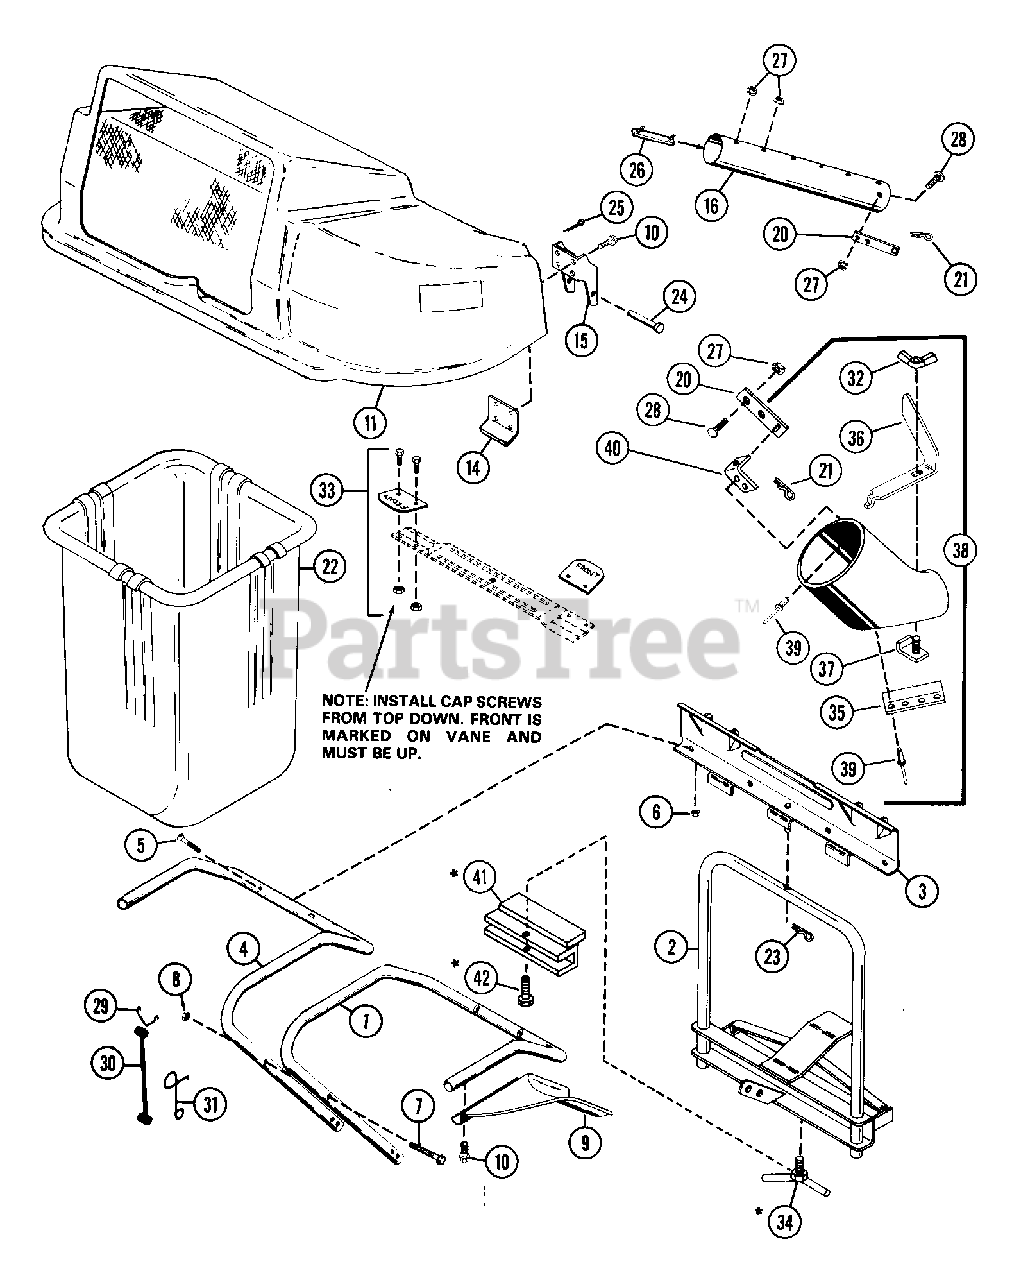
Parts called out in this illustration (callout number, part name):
1	TUBE R.H. SUPPORT
2	ATTACHMENT FRAME
4	TUBE L.H. SUPPORT
5	SCR-MCH .31-18X1.50 CROVCNTRS
6	NUT-LK-NYL.312-18 PL
7	BLT-HEX .25-20X2.25 GR2
8	NUT-LK-CTR .250-20 PL
9	SUPPORT TUBE
10	BLT-SCRHFWH .25-20X.62 PL
11	GRASS CATCHER COVER ASSEMBLY
14	RETAINER
16	TUBE BLANK
20	STRAP
21	PIN-HAIR INT .09X.188 PL
23	PIN-HAIR INT .08X.38X1.42 YWZC
24	CLEVIS PIN
25	PIN-COTR .06X.50
27	NUT-LK-FLG .250-20 PL
28	BLT-RDHDSQNK .25-20X.50 SHT PL
30	BATTERY STRAP
31	HOOK
32	NUT-WING W/INSERT .312 - 18
33	SERVICE VANE PACKAGE
34	T-HANDLE BOLT
35	EXTENSION CHUTE
36	BOOT STRAP
37	CLIP CONE
38	GRASS CATCHER BOOT ASSEMBLY
39	RVT-TBLR .187X.375 OH ST PL
40	RETAINER
41	ADAPTOR
42	BLT-HEX .50-13X2.25 PL GR5
